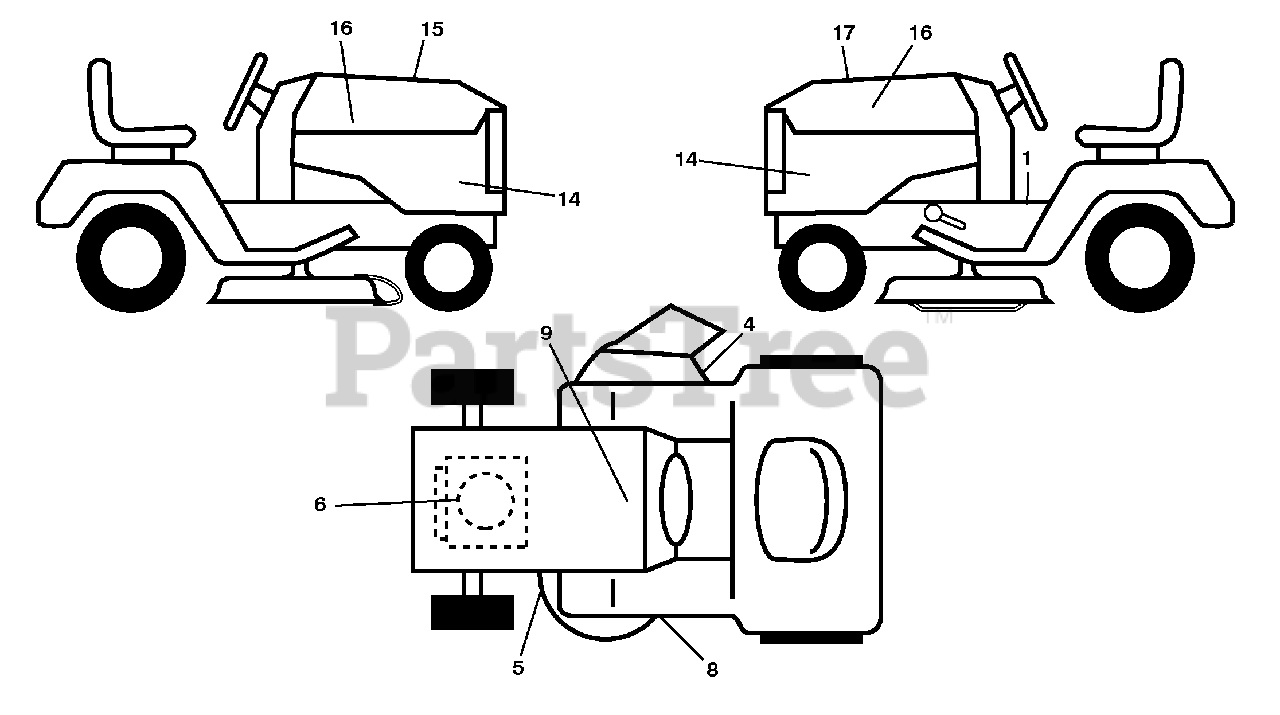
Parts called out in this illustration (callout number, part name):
1	Decal, Warning
4	Decal, Mower Warning
5	Decal, Caution
6	Decal, Eng.
8	Decal, Mower Sch.
9	Decal, Battery Dnge/Poi
14	Decal, Panel Side
15	Decal, Cust. Resp.
16	Decal, Hood Logo
17	Decal, Replacement
